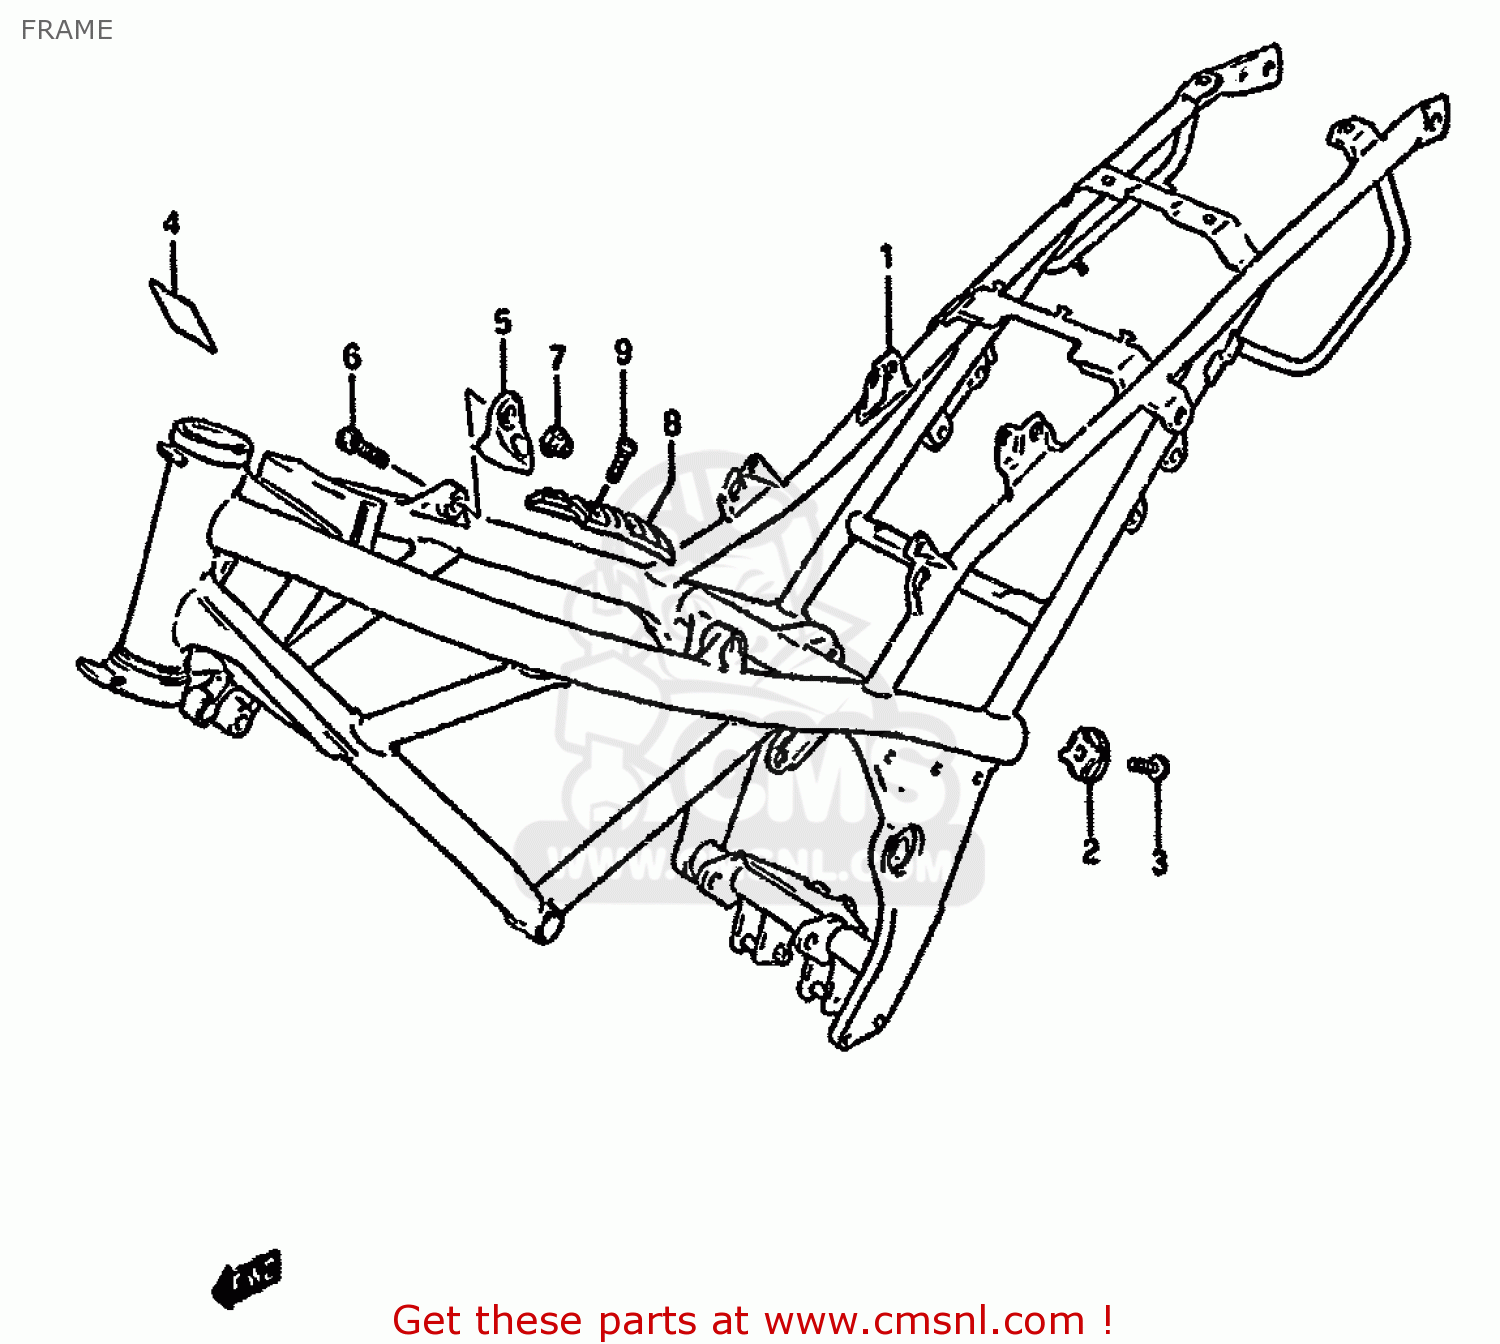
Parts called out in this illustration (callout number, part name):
1	FRAME
2	CAP,TANK RAIL END
3	SCREW
4	PROTECTOR,FRAME COVER FR
5	BRACKET,ENGINE MOUNT
6	BOLT, (10X30)
7	NUT
8	PROTECTOR,FUEL TANK,L
9	SCREW
